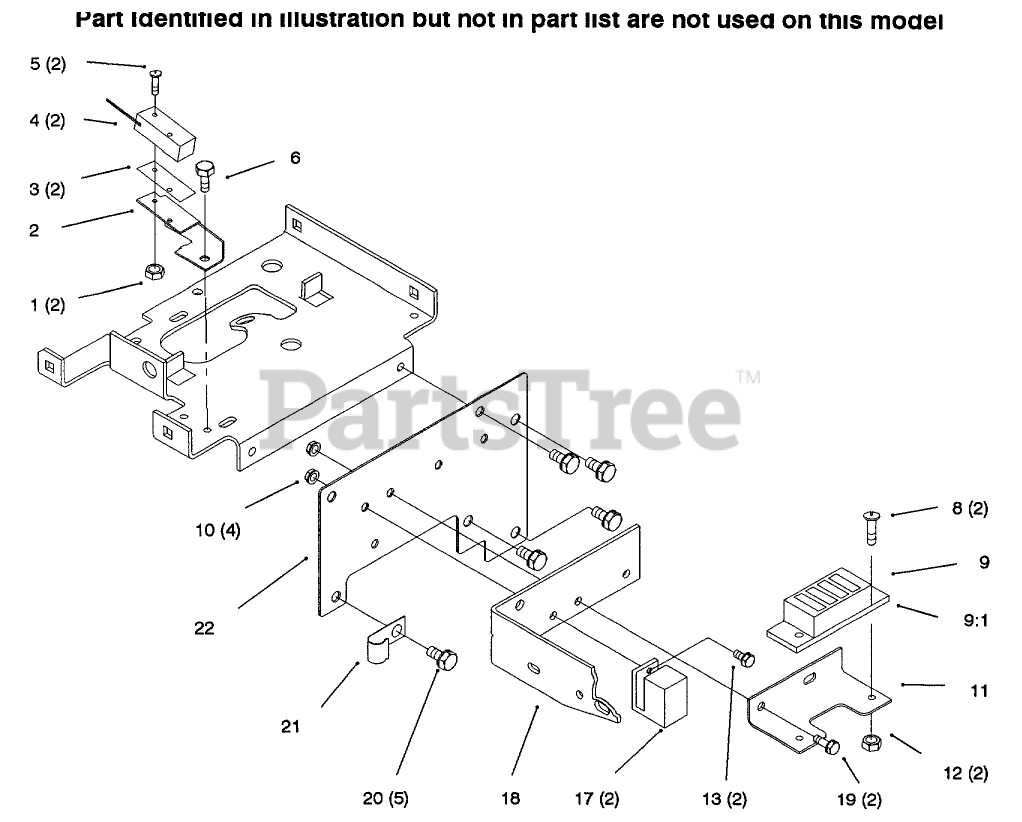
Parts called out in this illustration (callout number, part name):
1	NUT-HEX, NYL INS
3	BARRIER - SWITCH
4	SWITCH
5	SCREW-PHL 4-40X1 1/4
6	SCREW-HWH
8	SCREW-PAN
10	NUT-LOCK, NI
11	BRKT-FUS HLDER*B
17	RELAY
18	BRACKET-BELT*B
19	SCREW-HH
21	CLIP
